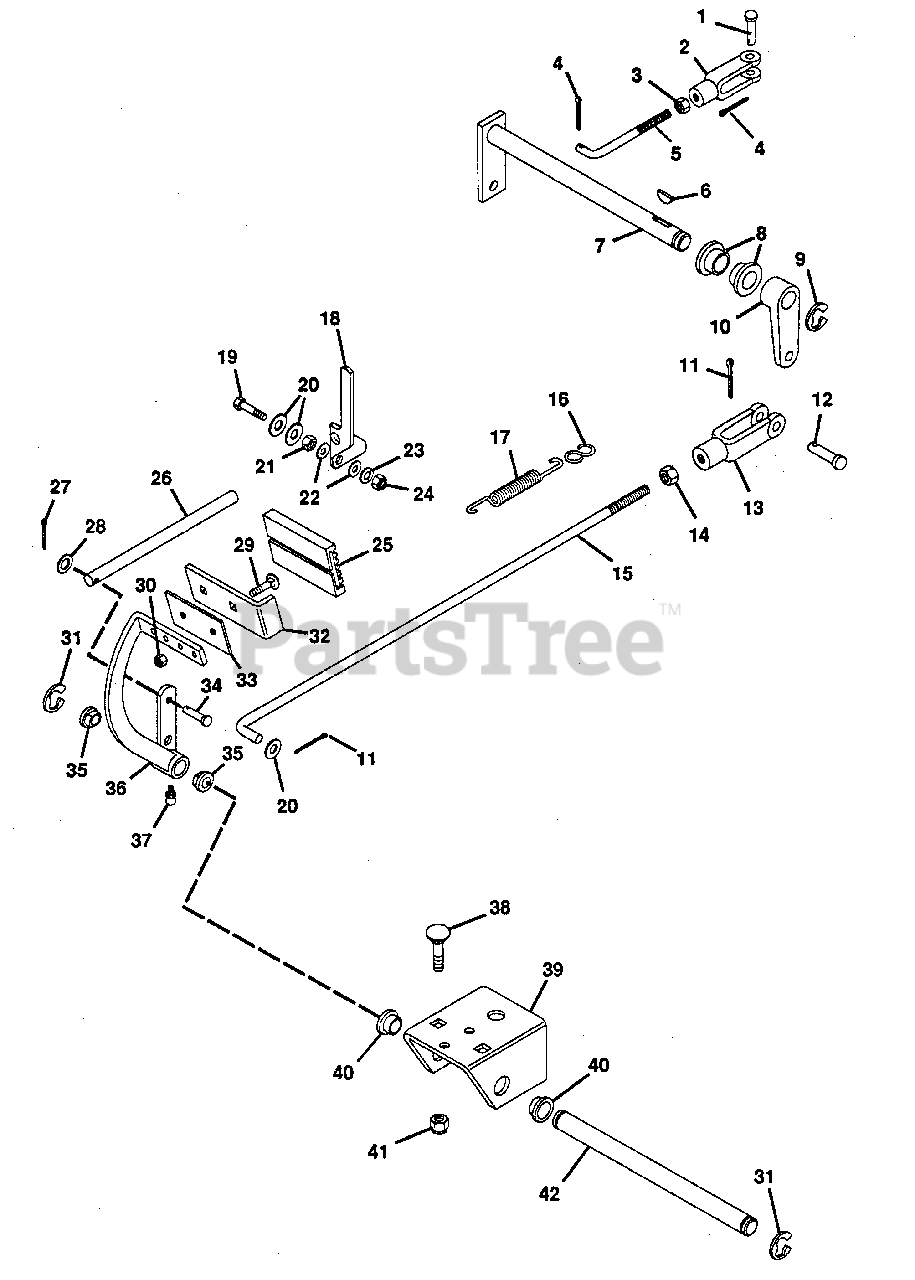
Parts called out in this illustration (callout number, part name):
1	PIN, CLEVIS 5/16X.812
2	YOKE
3	NUT, HEX 5/16-24
4	PIN, COTTER .09X.75
5	ROD, PARKING BRAKE
6	KEY, WOODRUFF .187X.75 HRD #9
7	WELDMENT, BRAKE CROSS SHAFT
8	BUSHING, NYLON .76X1.00X.76 FLG
9	E-RING, .750 SHAFT
10	LEVER, PTO
11	PIN, COTTER .125X.75
12	PIN, CLEVIS .375X.948
13	CLEVIS, 3/8-24 ADJUSTABLE
14	NUT, JAM 3/8-24
15	ROD, BRAKE
16	CLIP, SPRING
17	SPRING, EXT. 5.50X.50X20 RATE
18	ARM, PARKING BRAKE LOCK
19	BOLT, HEX 3/8-16X1.25
20	WASHER, FLAT .406X.812X.065
21	NUT, JAM 3/8-16 HEX
22	WASHER, NYLON .375X.75X.06
23	WASHER, LOCK 3/8
24	NUT, LOCK 3/8-16
25	PAD, PEDAL
26	ROD
27	PIN, COTTER .06X.75
28	WASHER, FLAT .281X.625X.065
29	BOLT, CARRIAGE 1/4-20X1.25
30	NUT, LOCK 1/4-20
31	E-RING, .625 SHAFT
32	PEDAL, BRAKE
33	PLATE, BRAKE
34	PIN, CLEVIS .25X1.03
35	BEARING
36	WELDMENT, BRAKE PEDAL
37	FITTING, LUBE 1/4-28
38	BOLT, CARRIAGE 3/8-16X.75
39	BRACKET, BRAKE PEDAL
40	BUSHING, NYLON .63X.873X.50
41	NUT, LOCK 3/8-16
42	SHAFT, BRAKE PEDAL MOUNTING
